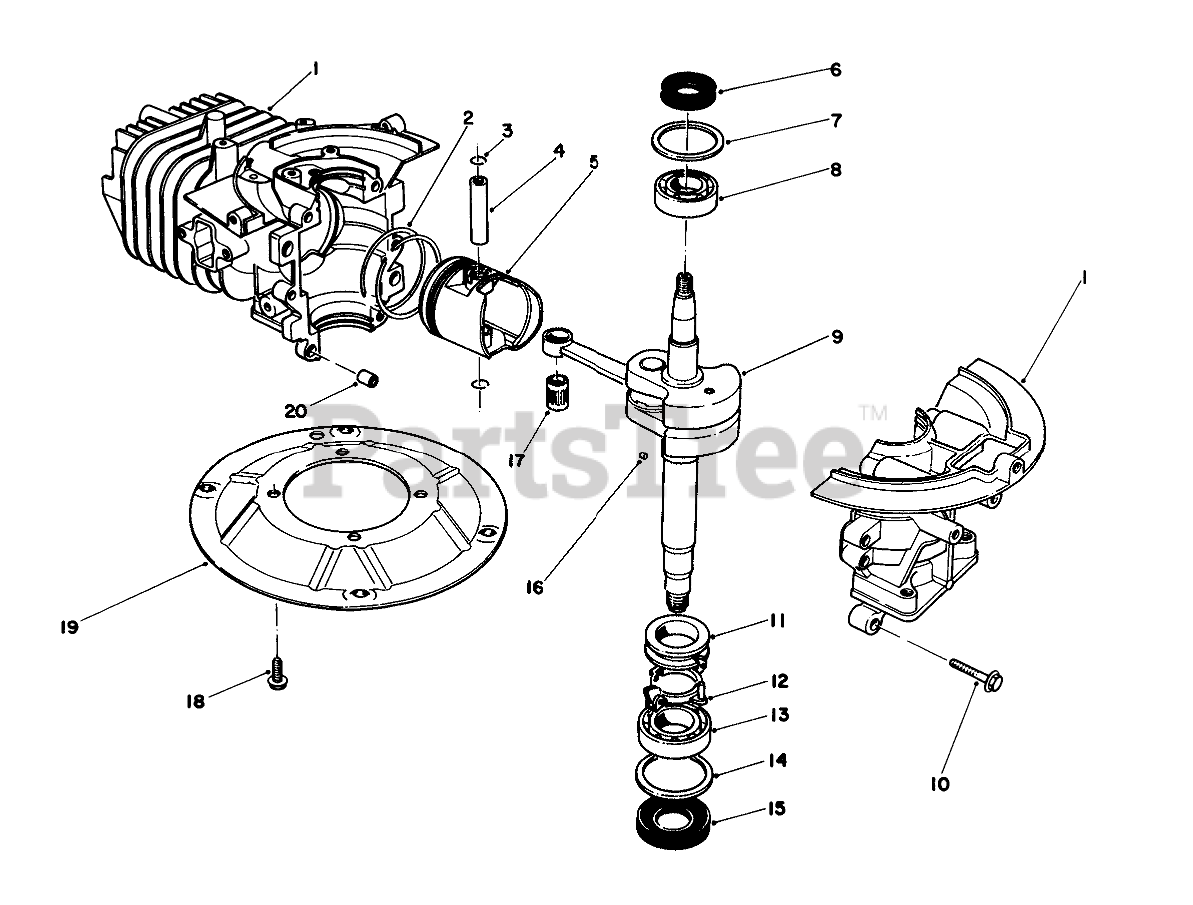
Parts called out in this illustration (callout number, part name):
1	CRANKCASE
2	RING SET
4	PIN-PISTON
5	Piston
6	OIL SEAL
7	WASHER-UPPER
8	BEARING-UPPER
9	CRANKSHAFT
11	SPACER
12	BRACKET
13	LOWER BRG
14	WASHER-LOWER
15	SEAL-OIL
17	BEARING
19	PLATE-MOUNTING
